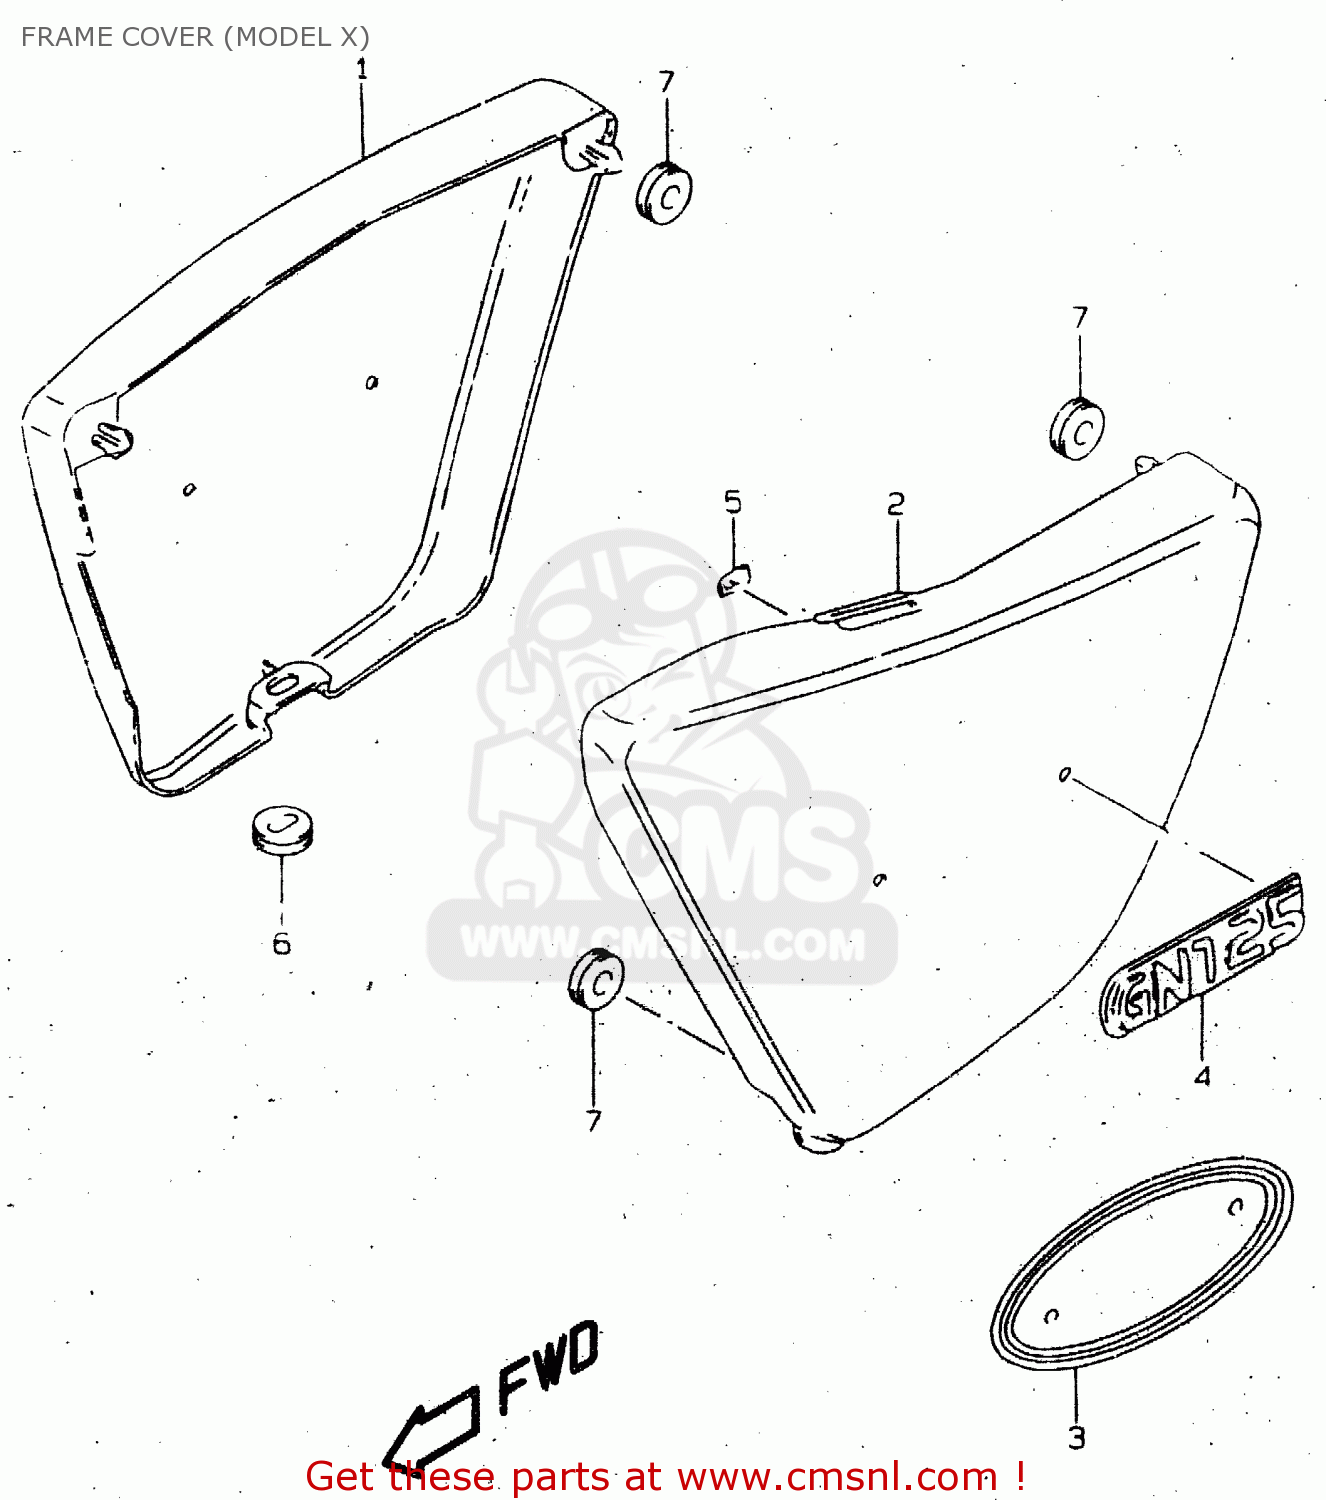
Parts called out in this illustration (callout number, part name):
1	COVER,FRAME,R(RED)
2	COVER,FRAME,L
3	TAPE,FRAME COVER
4	EMBLEM,FRAME COVER
5	NUT
6	CUSHION
7	CUSHION
